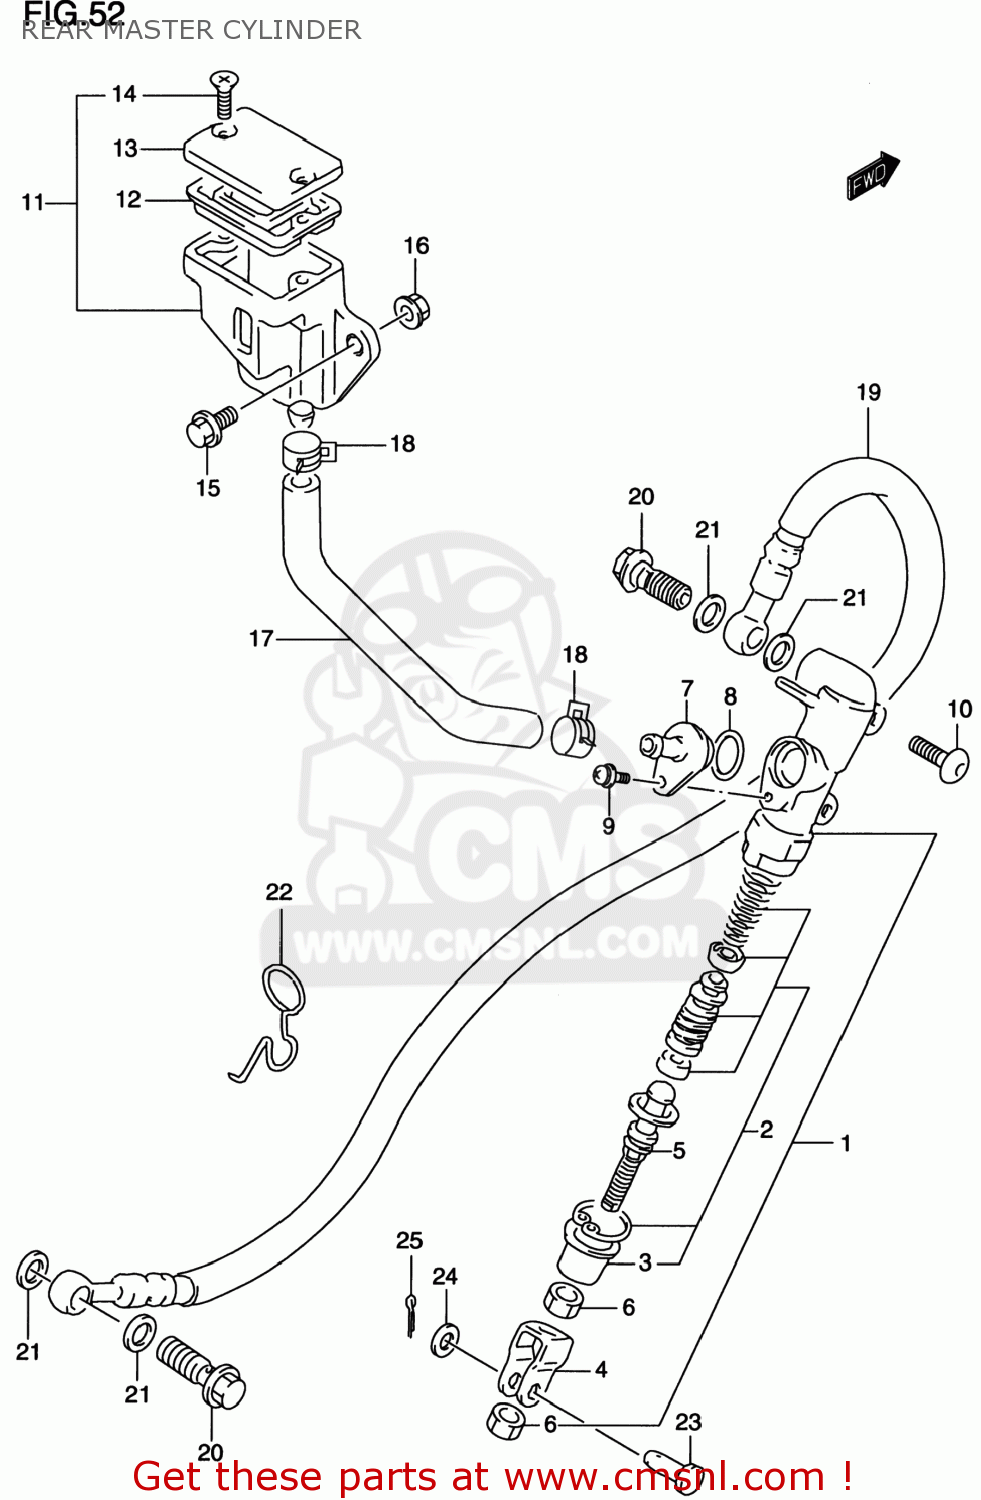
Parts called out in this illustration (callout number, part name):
1	CYLINDER ASSY,RR MASTER
2	PISTON/CUP SET
3	BOOT
4	YOKE
5	ROD,PUSH
6	NUT
7	CONNECTOR
8	O RING
9	SCREW
10	SCREW(6X25)
11	TANK ASSY,RR RESERVOIR
12	DIAPHRAGM
13	CAP
14	SCREW
15	BOLT
16	NUT
17	HOSE,RESERVOIR TANK
18	CLIP
19	HOSE,RR BRAKE
20	BOLT UNION
21	WASHER(10X15X1.5)
22	GUIDE,RR BRAKE HOSE
23	PIN
24	WASHER
25	PIN
